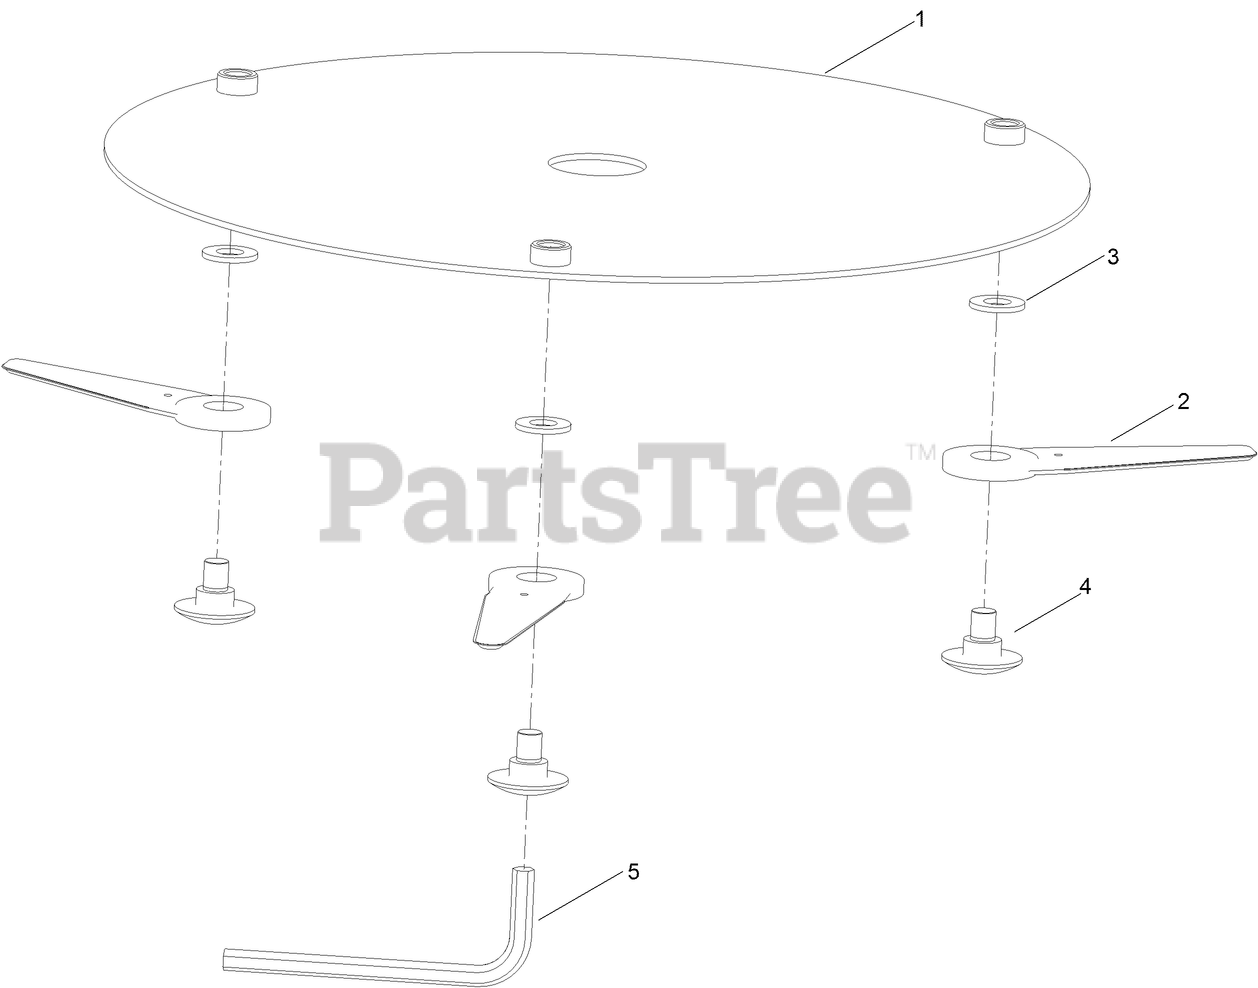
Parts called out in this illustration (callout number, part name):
1	18 INCH TRIM DISC
2	BLADE PLASTIC
3	WASHER-PLAIN
4	BOLT SHOULDER SPECIAL
5	WRENCH-HEX
